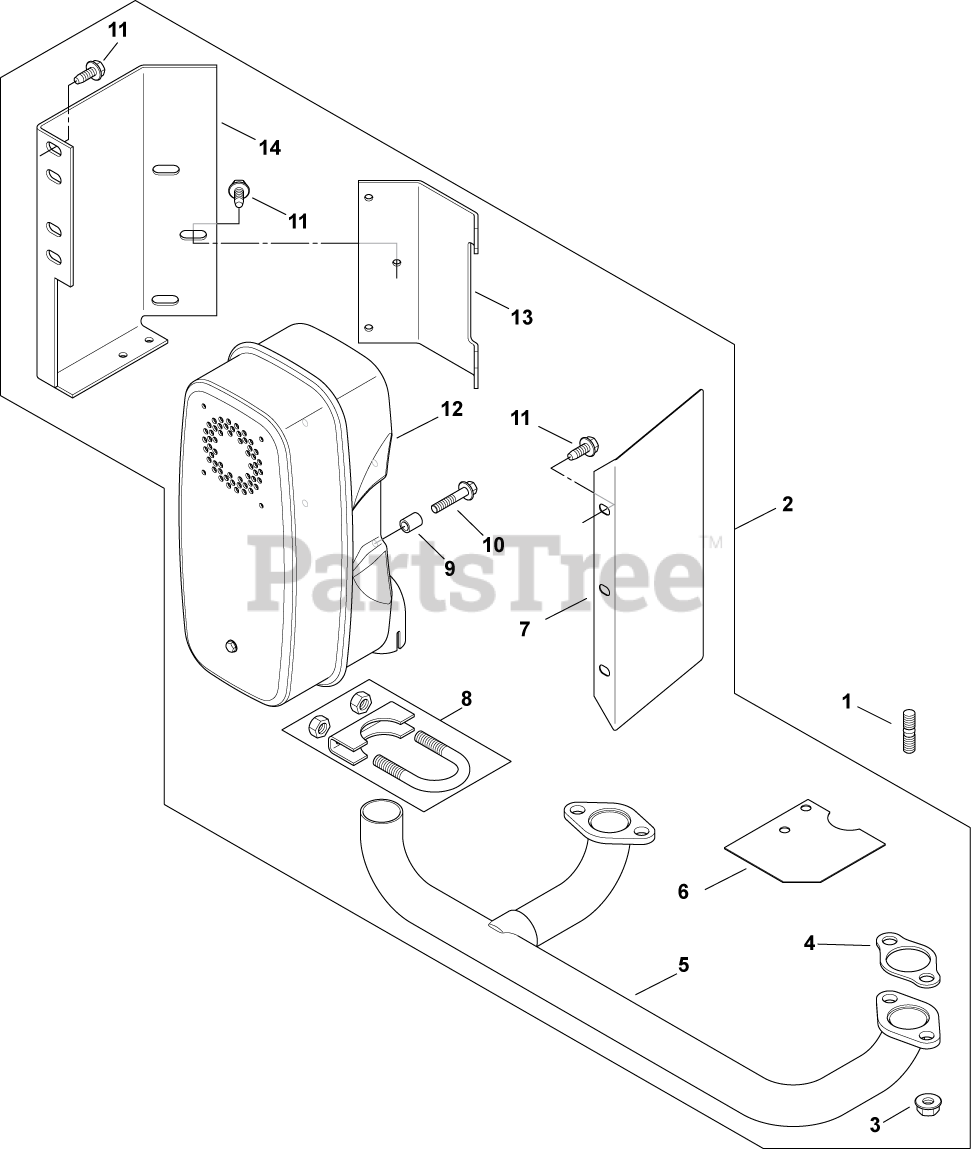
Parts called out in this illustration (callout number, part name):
1	STUD, EXHAUST-USE 25 072 24-S
2	KIT, MUFFLER MOUNTING
3	NUT, FLG M8X1.25
4	GASKET, EXHAUST
5	MANIFOLD, EXHAUST
6	DEFLECTOR, HEAT
7	DEFLECTOR, EXHAUST
8	CLAMP, MUFFLER
10	SCREW, FLG M6X1.0X30
11	SCREW,FLG THD FRM M6X1.0X16-(#25086397S)
12	MUFFLER USE 24 067 127-S
13	BRACKET, MUFFLER
14	BRACKET, MUFFLER
